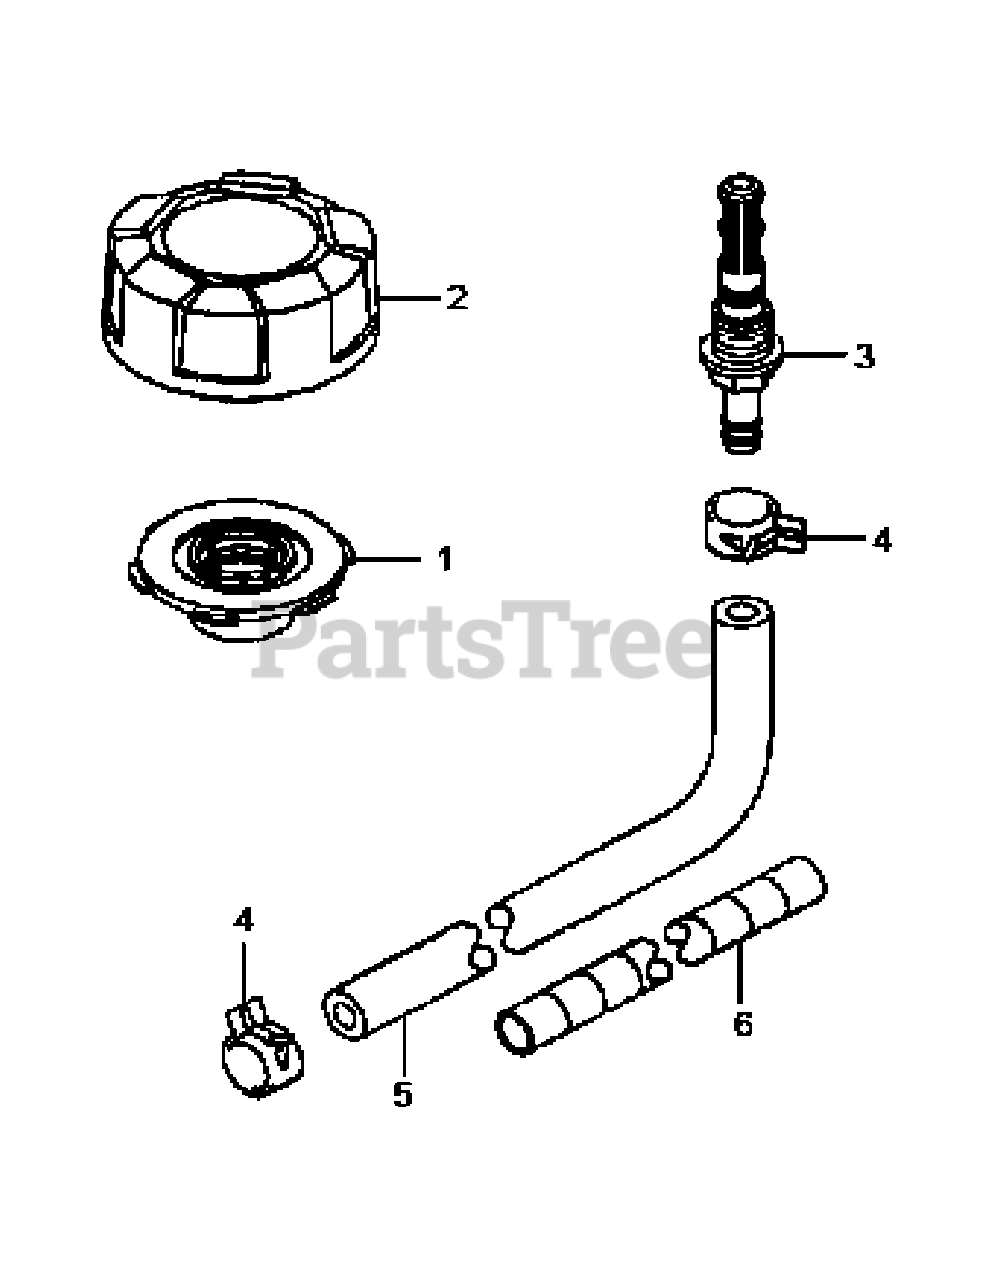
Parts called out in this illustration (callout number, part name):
3	Joint, In Tank Filter
4	Clamp
5	Tube, 6.35x12.7x285
